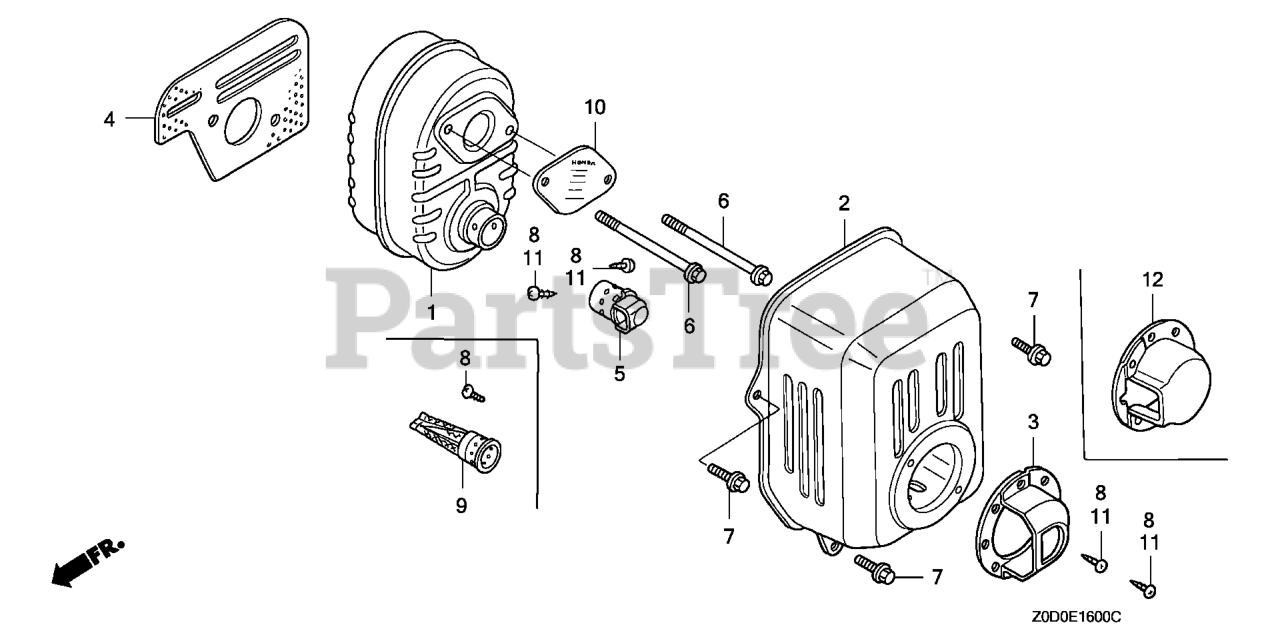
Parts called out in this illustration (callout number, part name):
1	MUFFLER
2	PROTECTOR, MUFFLER
3	CAP, MUFFLER (TO 1207644)
4	GASKET, MUFFLER
5	DEFLECTOR, MUFFLER (TO 1207644)
6	BOLT, FLANGE (6X79) (CT200)
7	BOLT, FLANGE (6X14)
8	SCREW, TAPPING (4X6) (TO INSTALL OPTIONAL SPARK ARRESTER)
9	ARRESTER, SPARK (TO 1207644)
10	PLATE, ARRESTER NUMBER (TO INSTALL OPTIONAL SPARK ARRESTER)
